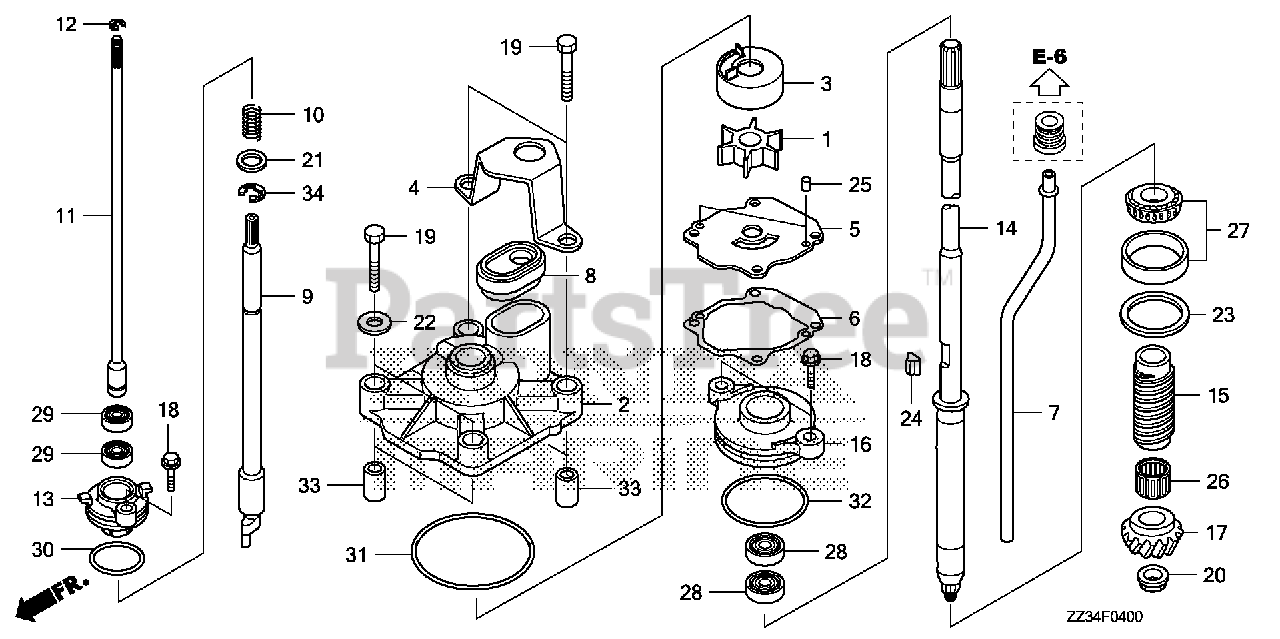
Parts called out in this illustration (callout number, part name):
1	IMPELLER, PUMP
2	HOUSING, IMPELLER
3	LINER, PUMP
4	HOLDER, WATER TUBE SEAL
5	COVER, IMPELLER
6	GASKET, IMPELLER
7	TUBE, WATER (XL)
8	RUBBER, WATER TUBE SEAL
9	ROD, SHIFT
10	SPRING, SHIFT ROD
11	ROD A, SHIFT (XL)
12	RING, STOPPER
13	HOLDER, SHIFT ROD
14	SHAFT, VERTICAL (XL)
15	SLINGER, OIL
16	HOUSING, WATER SEAL
17	GEAR, PINION (14T)
18	BOLT, FLANGE (6X20)
19	BOLT, HEX. (8X40)
20	NUT, SPECIAL (12MM)
21	WASHER, PLAIN (12MM)
22	WASHER (8MM)
23	SHIM, GEAR (40X46X0.10) (A)
23	SHIM, GEAR (40X46X0.15) (B)
23	SHIM, GEAR (40X46X0.30) (C)
23	SHIM, GEAR (40X46X0.50) (D)
24	KEY, WOODRUFF
25	PIN, DOWEL (6X10)
26	BEARING, NEEDLE (7/8X11/8X1)
27	BEARING (25X47X15)
28	SEAL, WATER (17X36X6)
29	SEAL, WATER (12X21X6)
30	O-RING (33.7X3.5)
31	O-RING, WATER PUMP
32	O-RING (58.5X3.5)
33	COLLAR, DISTANCE
34	E-RING (10MM)
